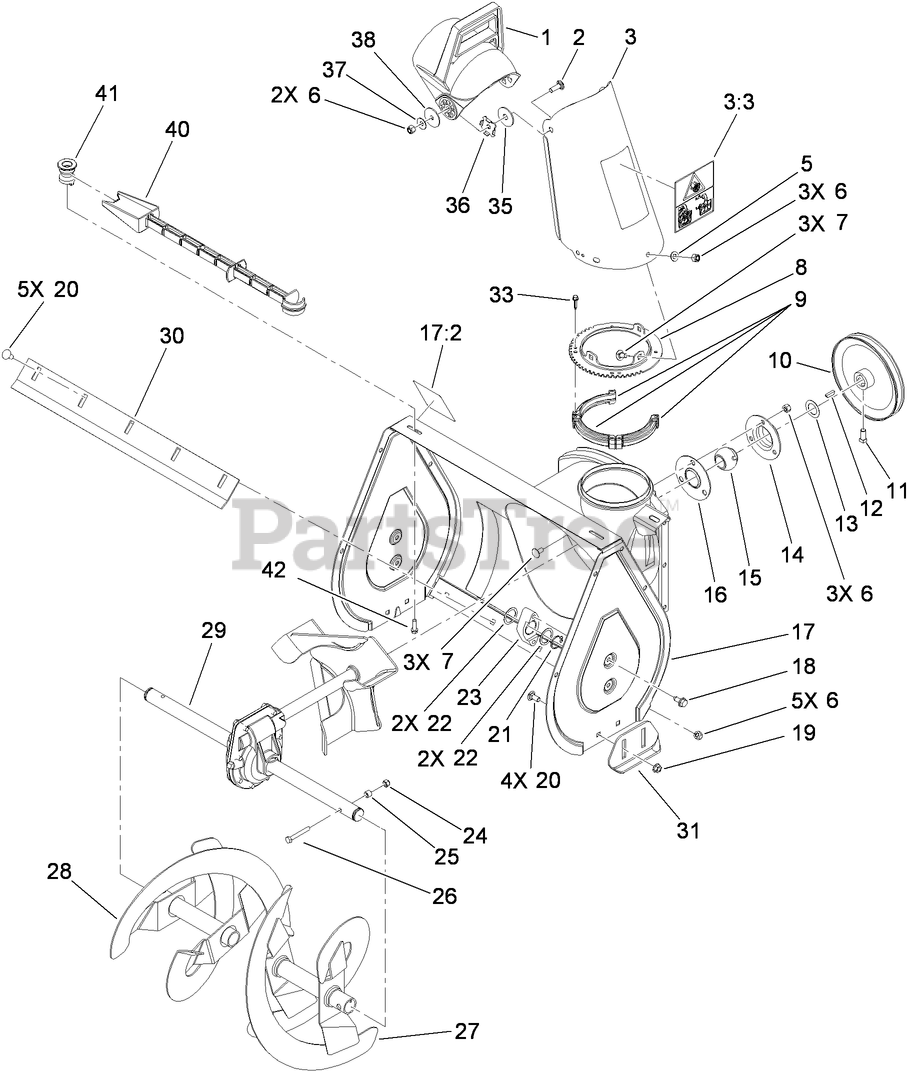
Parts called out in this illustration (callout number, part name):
1	CHUTE-DEFLECTOR
2	SCREW-CARR
3	CHUTE ASM
3:3	DECAL-DANGER, DISCHARGE
5	WASHER-PLAIN
6	NUT-LOCK, NI
7	SCREW-CARR
8	RING-CHUTE
9	RING-CHUTE, RETAINER
10	PULLEY
11	SCREW-SET, SQH
12	KEY-WOODRUFF
13	WASHER
14	FLANGE-CUP, BEARING
15	BEARING-BALL
16	FLANGE-CUP, BEARING
17	AUGER HOUSING ASM
17:2	DECAL-DANGER
18	SCREW-HWHTF
19	NUT-HF
20	BOLT-CARR
21	RING-RETAINING
22	WASHER
24	NUT-LOCK, NI
25	SPACER
26	SCREW-HH
27	AUGER-LH
28	AUGER-RH
29	22 INCH GEAR CASE ASM
30	BLADE-SCRAPER
33	SCREW-SPECIAL
35	WASHER-RUBBER
36	PLATE-FRICTION
37	WASHER-BELLEVILLE
38	WASHER-FLAT
40	STICK-CLEANOUT
41	HOLDER-STICK
42	SCREW-HWH
